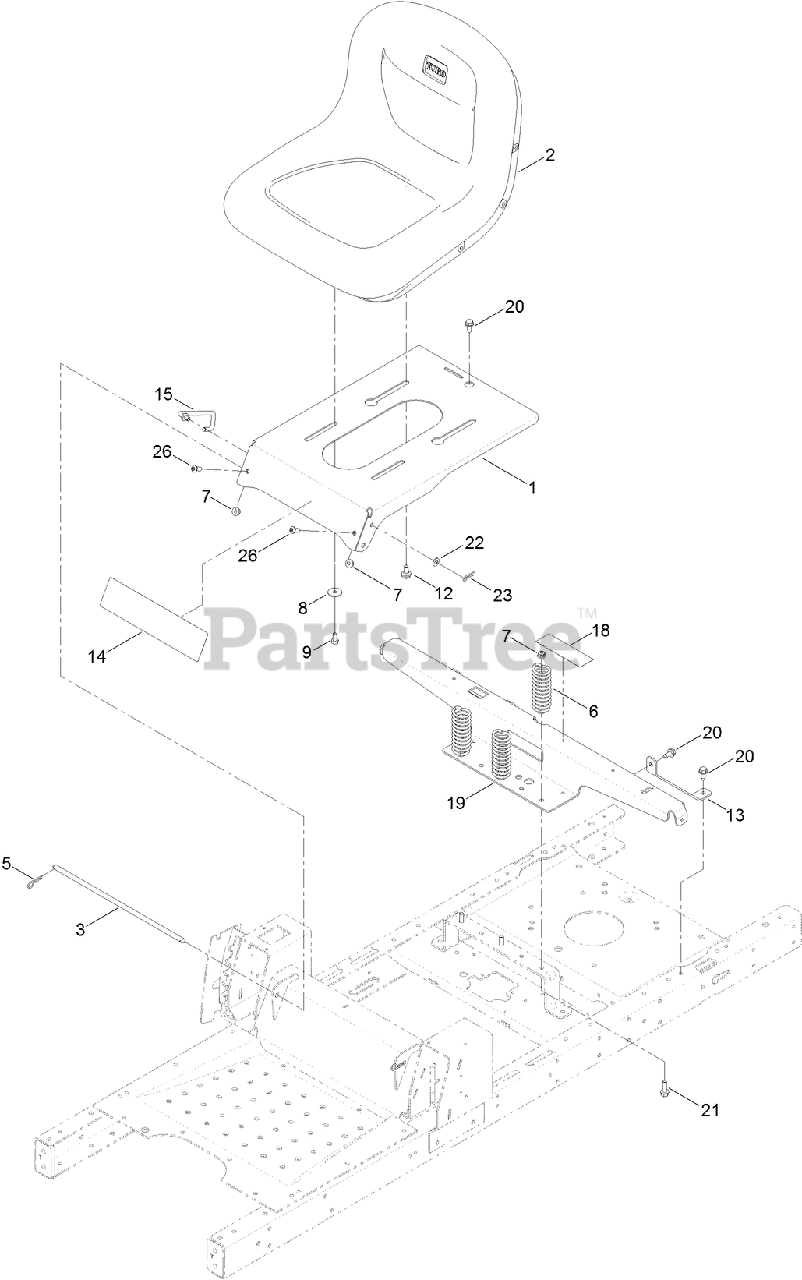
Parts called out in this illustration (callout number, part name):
1	PAN-SEAT
2	SEAT-15 INCH
3	ROD-PIVOT, NARROW
5	PIN-COTTER
6	SPRING-COMPRESSION
7	NUT-HF, NI
8	WASHER-PIVOT
9	SCREW-HH
12	BOLT-SHOULDER,HFH
13	SUPPORT-TANK, REAR
14	DECAL-TIMECUTTER
15	STOP-SEAT
18	DECAL-SERVICE, CE
19	SUPPORT-POD
20	SCREW-HWHTF
21	SCREW-HHF
22	WASHER-PLAIN
26	SCREW-HSBH
